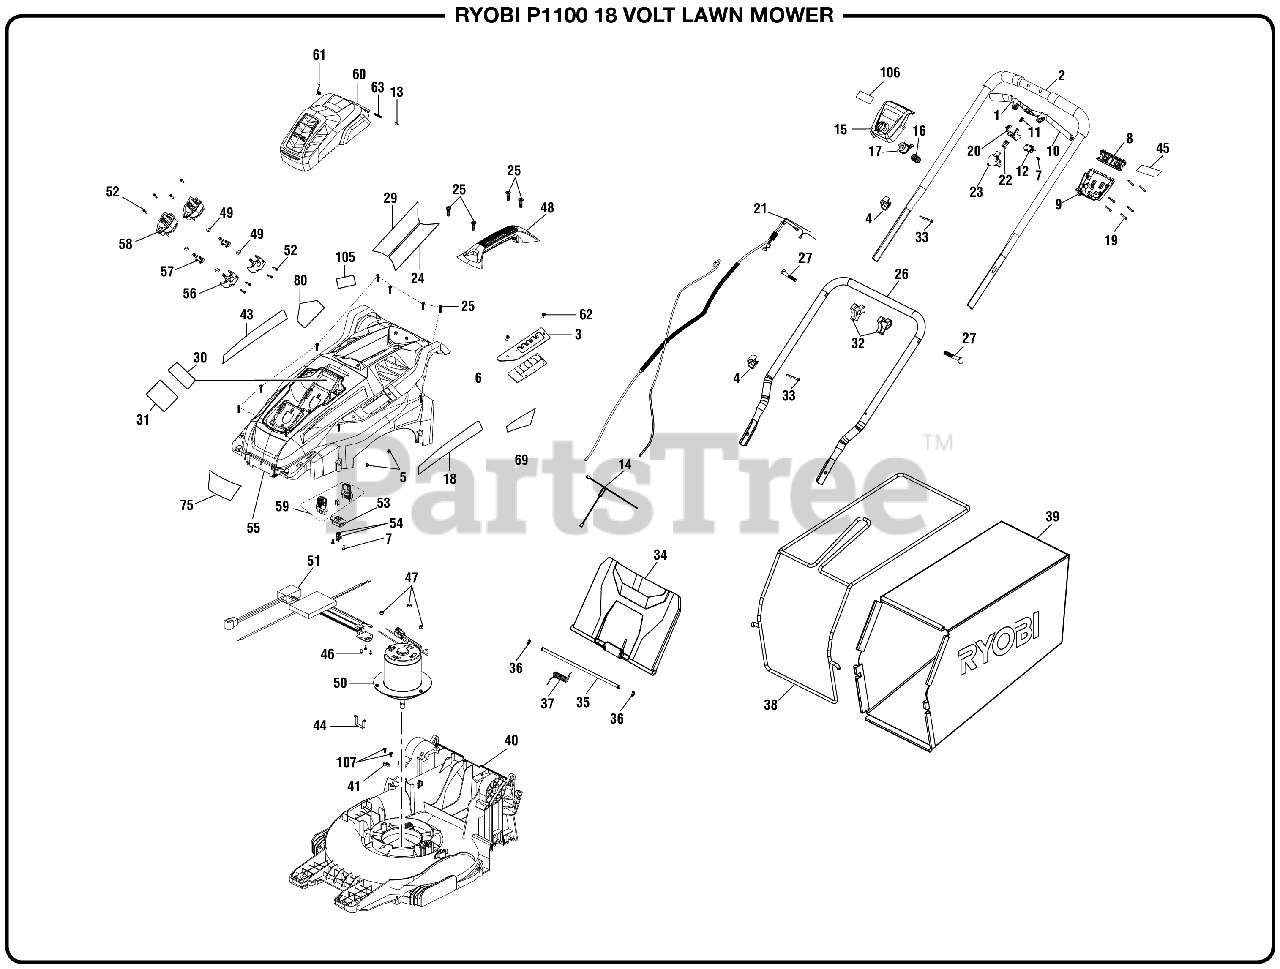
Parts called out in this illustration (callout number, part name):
1	Trigger Handle (Right Power Lever)
2	Upper Handle Assembly
3	Height Adjustment Plate
4	Cord Clamp
5	Lock Nut (M5 x 0.8 mm)
6	Dust Gasket
7	Screw (M4 x 10 mm, T20 Torx Pan Hd.)
8	Lower Cover (Stain Handle)
9	Lower Cover (Trigger Housing)
10	Trigger Handle (Left Power Lever)
11	Compression Spring (Trigger)
12	On/Off Switch
13	Battery Door Axle
14	Lead Wire w/Terminal Block
15	Upper Cover (Control Assembly)
16	Handle Adjustment Spring
17	Safety Button
18	Lithium Label (Left)
19	Screw (M4-18 x 30 mm, T15 Torx Soc. Hd.)
20	Slider (Switch Box)
21	Starter Cable (Long)
22	Compression Spring (Trigger Handle)
23	Switch Holder
24	Warning Icon Label (Right)
25	Screw (M4 x 20 mm, T20 Torx Pan Hd. S.T.)
26	Lower Handle
27	Screw (M8 x 57 mm)
29	Warning Icon Label (Left)
30	Start Key Label (Eng)
31	Start Key Label (FR/SP)
32	Knob (526906001)
33	Screw (M3 x 20 mm, Pan Hd.)
34	Rear Discharge Door
35	Rear Door Axle
36	Retaining Ring (E)
37	Torsion Spring (Rear Door)
38	Bag Frame
41	Wire Press Plate
43	Lithium Label (Right)
44	Mounting Bracket
45	Starting Instructions Label
46	Screw (M3 x 8 mm, Pan Hd., Pan Hd)
47	Lock Nut (M6)
49	Rubber Cushion
51	Soft Start Circuit Board
52	Screw (M4 x 16 mm, T20 Torx Socket Pan Hd.)
53	Key Holder
54	Female Terminal
55	Deck Cover
56	Press Cover (Battery Connect)
57	Plate (Battery Connect)
58	Base (Battery Connect)
59	Start Key
60	Battery Cover
61	Torsion Spring (Battery Door)
62	SCREW (M5 x 16 mm SOC. WASHER HD. CAP)
63	Compression Spring
69	Cut Diameter Label (Left)
75	Ryobi Logo Label (Handle)
80	Danger Label (No Hands/Feet)
105	Data Label
106	Ryobi Logo Label (Handle)
107	Screw (M4 x 16 mm, T20 Torx Pan Hd.).
